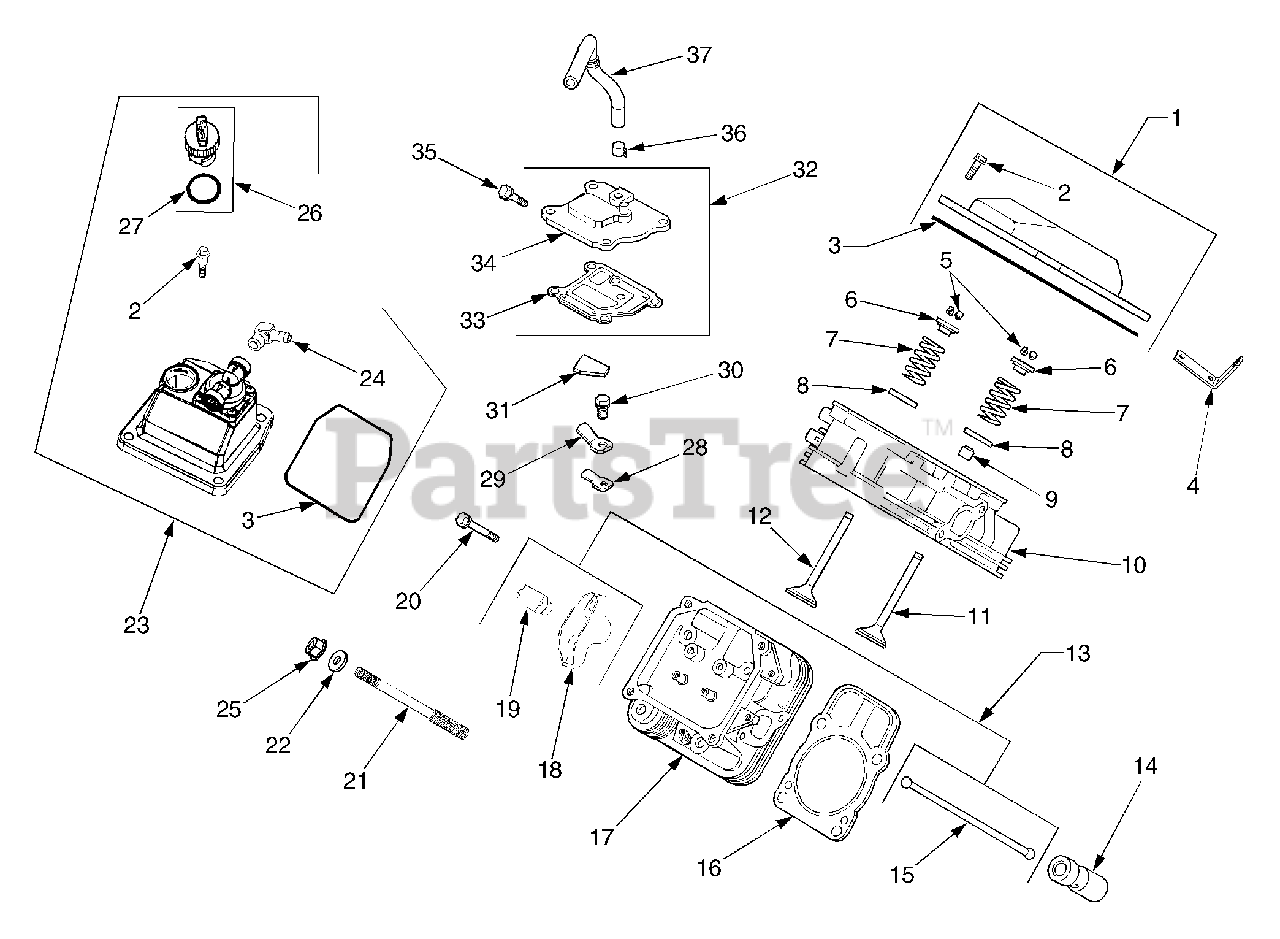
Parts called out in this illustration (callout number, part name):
1	Kit, Valve Cover
2	Screw, Hx. Flng, M6 x 1.0 x 30
3	O-Ring, Valve Cover
4	Strap, Lifting
5	Kit, Retainer
6	Cap, Valve Spring
7	Spring, Valve
8	Retainer, Spring
9	Seal, Valve Stem
10	Kit, Cylinder Head #1
11	Valve, Intake Std
12	Valve, Exhaust Std
13	Kit, Valve Train
14	Lifter, Valve
16	Kit, Cylinder Head Gasket
17	Kit, Cylinder Head #2
19	Pivot, Rocker Arm
20	Screw, Hex Flng, M6 x 1.0 x 34
21	Stud, Cylinder Head
23	Cover Kit, Fuel Pump Valve
24	Connector, 90°.
25	Nut, Hex Flange, M8 x 1.25
26	Cap Assembly, Oil Fill
27	O-Ring
28	Reed, Breather
29	Retainer, Breather Reed
30	Screw, Hex Flng, M5 x 0.8 x 10
31	Filter, Breather
32	Kit , Breather
33	Gasket, Breather
34	Cover, Breather
35	Screw, Hex Flng M6 x 1.0 x 20
36	Clamp, Breather
37	Hose, Breather
